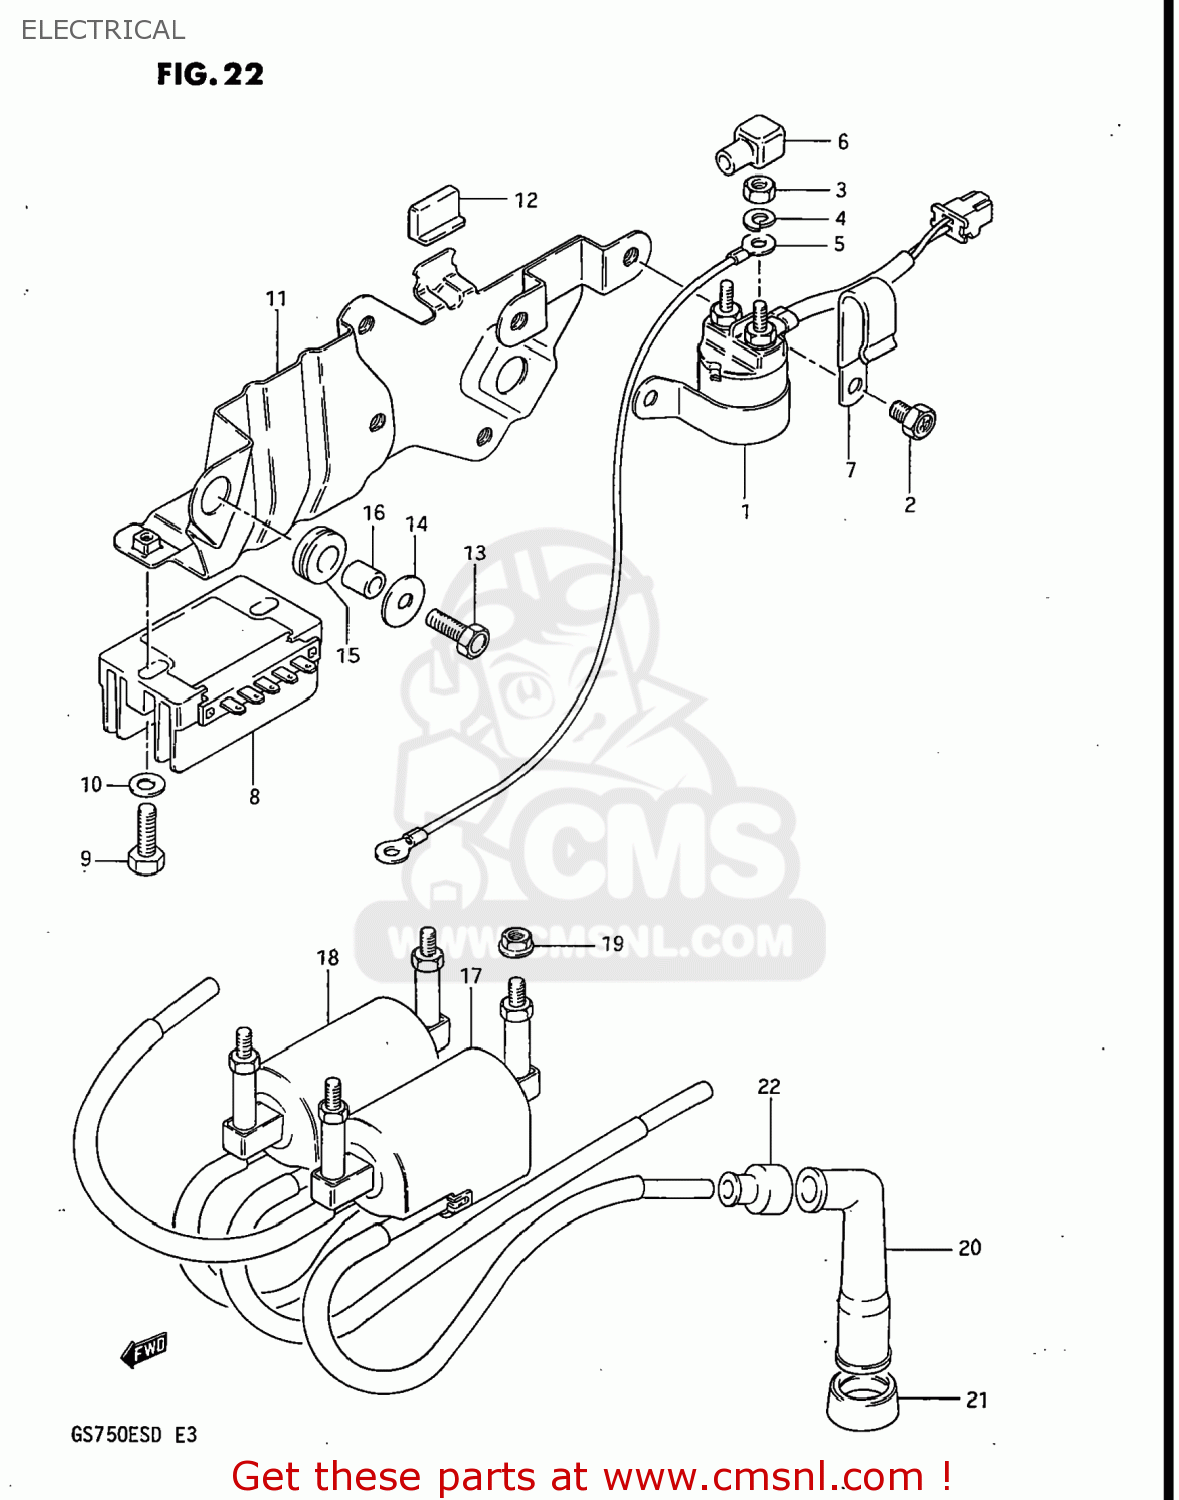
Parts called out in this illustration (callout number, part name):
1	RELAY ASSEMBLY,STARTING MOTOR
2	SCREW(6X10)
3	NUT 6MM
4	LOCK WASHER
5	WIRE,STARTER MOTOR LEAD
6	CAP,STARTER MOTOR TERMINAL
7	CLAMP
8	RECTIFIER ASSEMBLY
9	BOLT(6X20)
10	WASHER
11	HOLDER COMP,ELECTRONIC PARTS
12	CUSHION,FRAME COVER
13	CUSHION
14	BOLT, UPPER
15	WASHER (6.5X20X1.2)
16	CUSHION
17	SPACER(6.1X9X7.5)
18	COIL ASSEMBLY,IGNITION
19	COIL ASSEMBLY,IGNITION NO
20	NUT
21	CAP,SPARK PLUG
22	SEAL,SPARK PLUG
23	SEAL,SPARK PLU
